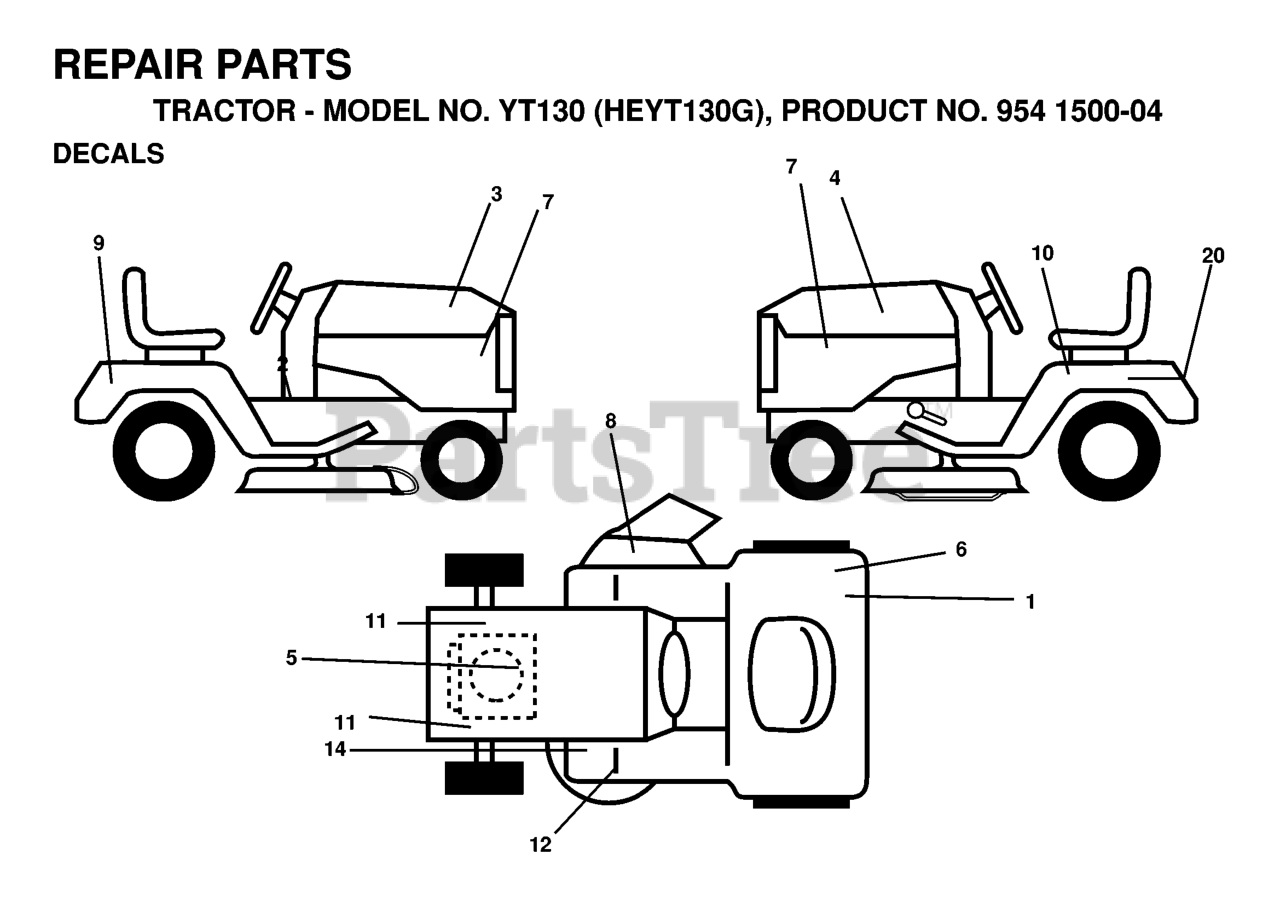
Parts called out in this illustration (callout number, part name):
1	DECAL CERTIFICATION
2	DECAL PARK BRAKE
3	DECAL HD RH YT130
4	DECAL HD LH YT130
5	DECAL HP ENGINE
6	DECAL EUROPE STANDARD CE
7	DECAL PNL SIDE
8	DECAL MOWER CUT/FINGER
9	DECAL FENDER HUSQ
10	DECAL READ OWNER'S MAN SYMS
11	DECAL
12	DECAL
14	DECAL V BELT SCHEMATIC
20	DECAL BTRY SYMBOLS
